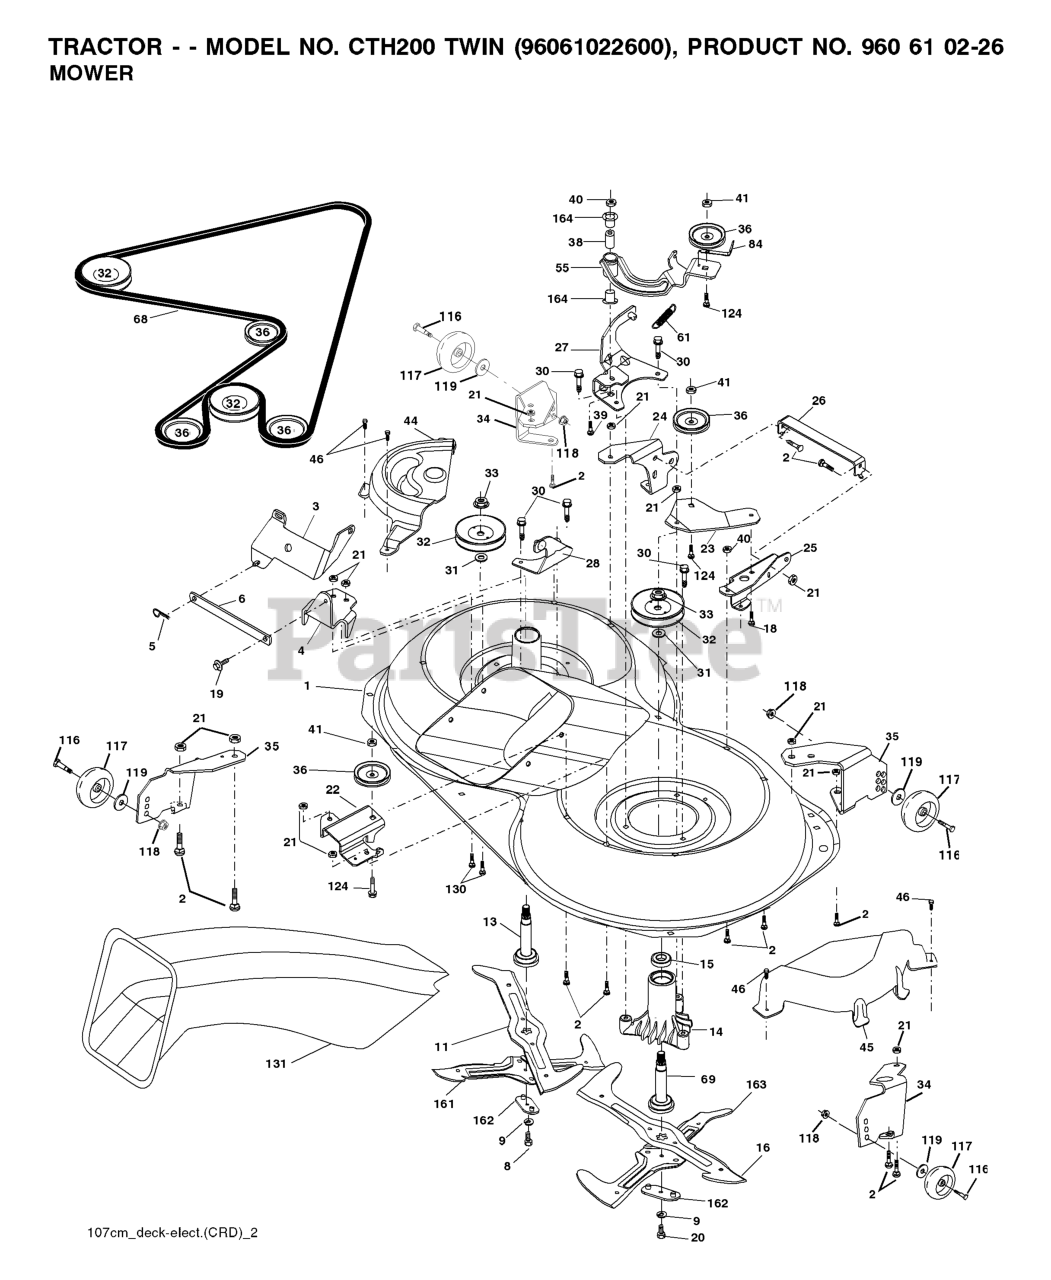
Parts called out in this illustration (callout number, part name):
1	Housing Asm. Mower 107 CRD
2	RP BOLT 5/16-18 X3/4 ZN/YEL GR
5	RETAINER-SPRNG RB
6	BAR.SWAY.92.CRD
8	BOLT.3/8-24X1.25 GR8
9	LOCKWASHER
11	BLADE.3N1.LH.CRD
13	SHAFT.ASM.W/LWR.BRG.RH.THREAD
14	HOUSING.MANDREL.VENTED (MACHD)
16	BLADE.3N1.RH.CRD
19	BOLT SHD 5/16-18
20	BOLT.3/8-24X1.25GR8. LHTHRD
21	LOCKNUT
22	BRACKET.IDLER.RR.107.CRD
24	BRACKET
25	BRACKET RF
26	SUPPORT
28	BRACKET
30	SCREW, WASHER HEAD
31	WASHER.SPACER.MANDREL
32	PULLEY.MANDREL.4.80 PD.2006
33	NUT.FLANGE.LOCK.TOP
34	BRACKET
35	BRACKET
36	PULLEY.IDLER.4.25
41	NUT LOCK FLG 3/8-16 UNC
45	COVER.MANDREL.RH.CRD
46	SCREW.1/4-20X5/8
55	ARM.IDLER.107.CRD
61	SPRING
68	HEX-BELT 107 MOWER
69	SHAFT ASM VENT
84	KEEPER, BELT IDLER
116	BOLT.SHOULDER.3/8-16X3-5/8.
117	RP WHEEL. GUAGE RALLY
118	NUT LOCK FLG 3/8-16 UNC
119	WASHER
124	BOLT.3/8-16X1.50
130	BOLT.CARR.SQNK.5/16-18UNC.X3/4
131	CHUTE BAGGER
163	BLADE.CROSS.RH.CRD.107
164	BRNG T
